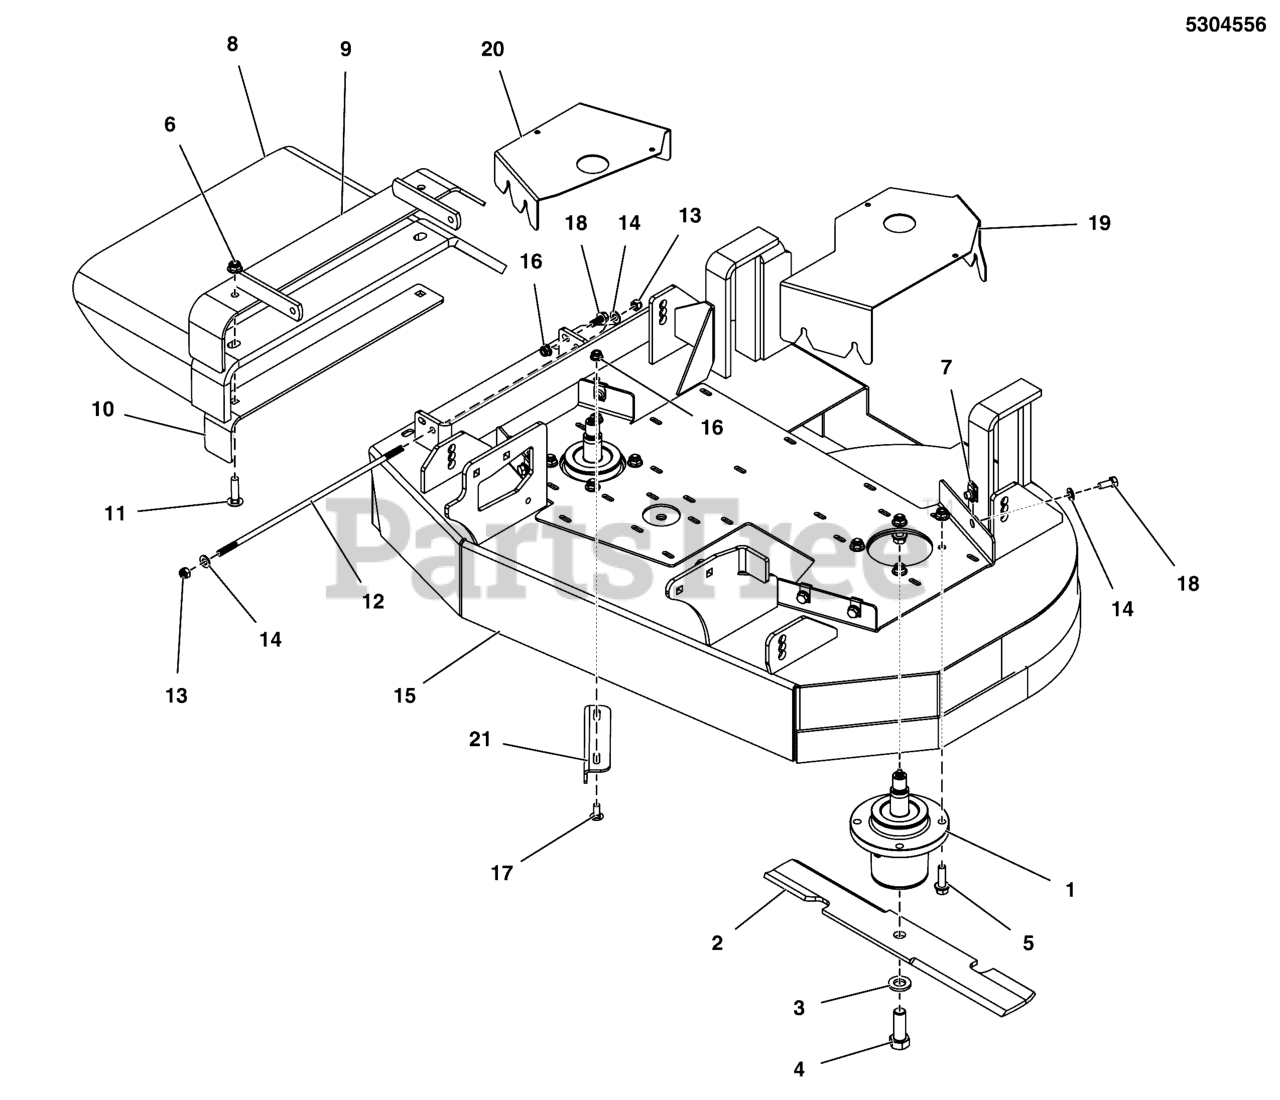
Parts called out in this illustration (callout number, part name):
1	SPINDLE, ASSM, ALUMINUM - 5.25
2	BLADE SET, 36 DECK (2)
3	WASHER, BLADE BOLT, 9/16" F436, CZ
4	BOLT, 5/8-11 X 1-3/4 GD8
5	BOLT, 3/8-16 X 1-1/4, FLANGE, GD 5, CZ
6	NUT, 3/8 - 16 HEX NYLOCK FLANGE
7	BODY CLIP, 5/16-18-7GA MATERIAL
8	CHUTE, RUBBER DISCHARGE CHUTE (5104441)
9	WELD, MOUNT, DISCHARGE CHUTE - BLK
10	SUPPORT, DISCHARGE CHUTE - BLK
11	BOLT, 3/8-16 X 1-1/2, CARRIAGE, GD5, CZ
12	ROD, 5/16 X 13.75, TBE, CZ
13	NUT, 5/16-24 HEX NYLON LOCK
14	WASHER, 5/16" SAE
15	DECK SHELL W/DECALS, 36, SRSZ1 (5415399B)
16	NUT, 5/16-18 HEX NYLOCK FLANGE NUT
17	BOLT, 5/16-18 X 3/4, CARRIAGE, GD5, CZ
18	BOLT, 5/16-18 X 3/4 GD5
19	GUARD, MOWER DECK, LH 36
20	GUARD, MOWER DECK, RH 36
21	PLATE, DEFLECTOR, 36" - BLK
